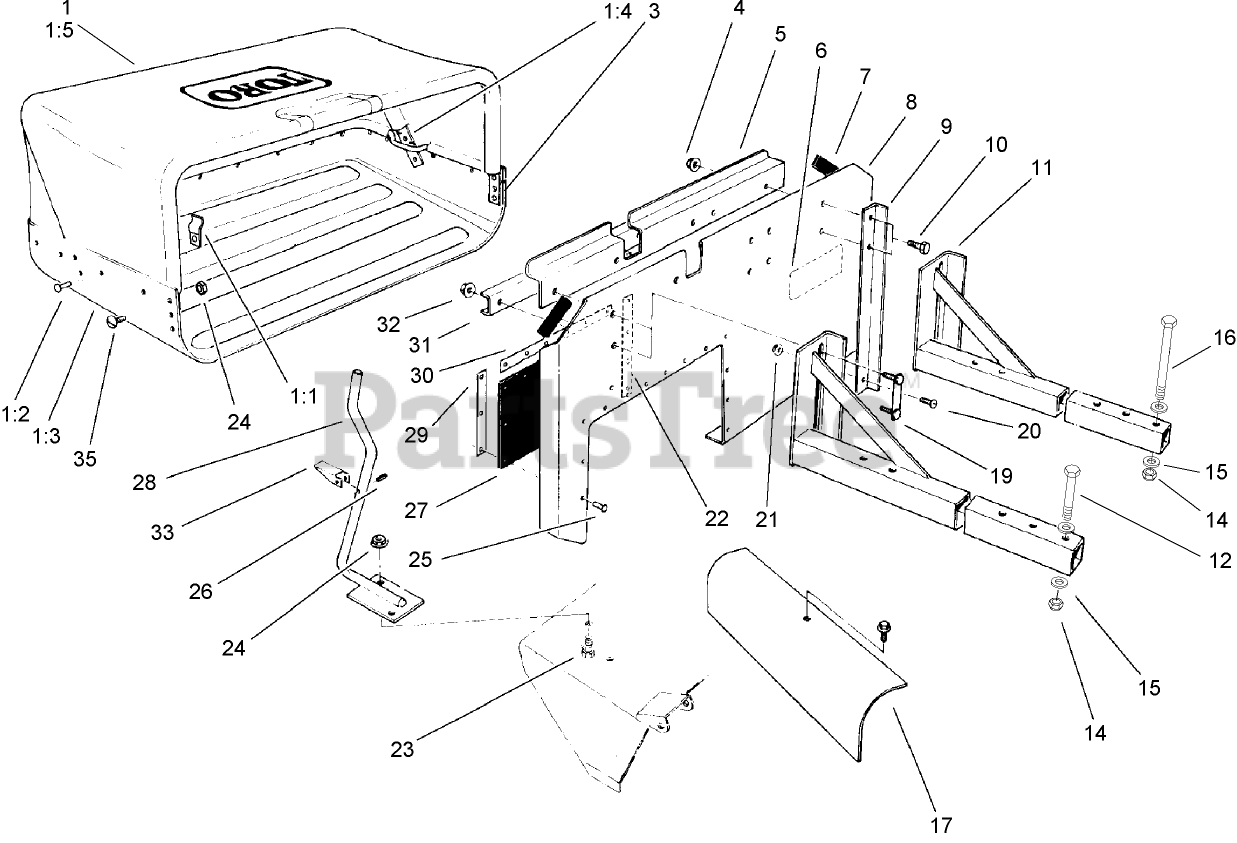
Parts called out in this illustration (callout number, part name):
1	BAG TRAY ASM
1:1	CLIP-HALF
1:2	RIVET-BLIND
1:3	TRAY-BAG, GRASS
1:4	Rod-Cloth
1:5	Bag-Cloth
3	TUBE-SUPPORT, BAG
4	NUT-HHF, WHIZ
5	SUPPORT-ATTACHMENT, BAG
6	DECAL-DANGER
7	PAD-RUBBER
8	PANEL-BACK
9	SUPPORT-PANEL, LH
10	SCREW-HH
11	MOUNT-BEAM
12	SCREW-HH
14	NUT-LOCK, NI
15	WASHER-FLAT
16	SCREW-HH
17	BAFFLE-52IN
17	BAFFLE-44IN
19	Retainer-Bolt
21	NUT-HF
22	STRIP-Seal, 10in
23	SCREW-HH
24	NUT-HF
25	RIVET-POP
26	PIN-SPRING
28	ROD-LOCKUP
29	STRIP
30	STRIP-SEAL, 16in
31	SUPPORT-CHANNEL
32	NUT-LOCK, FLANGE
33	LATCH-LOCKUP
35	SCREW-PPH
